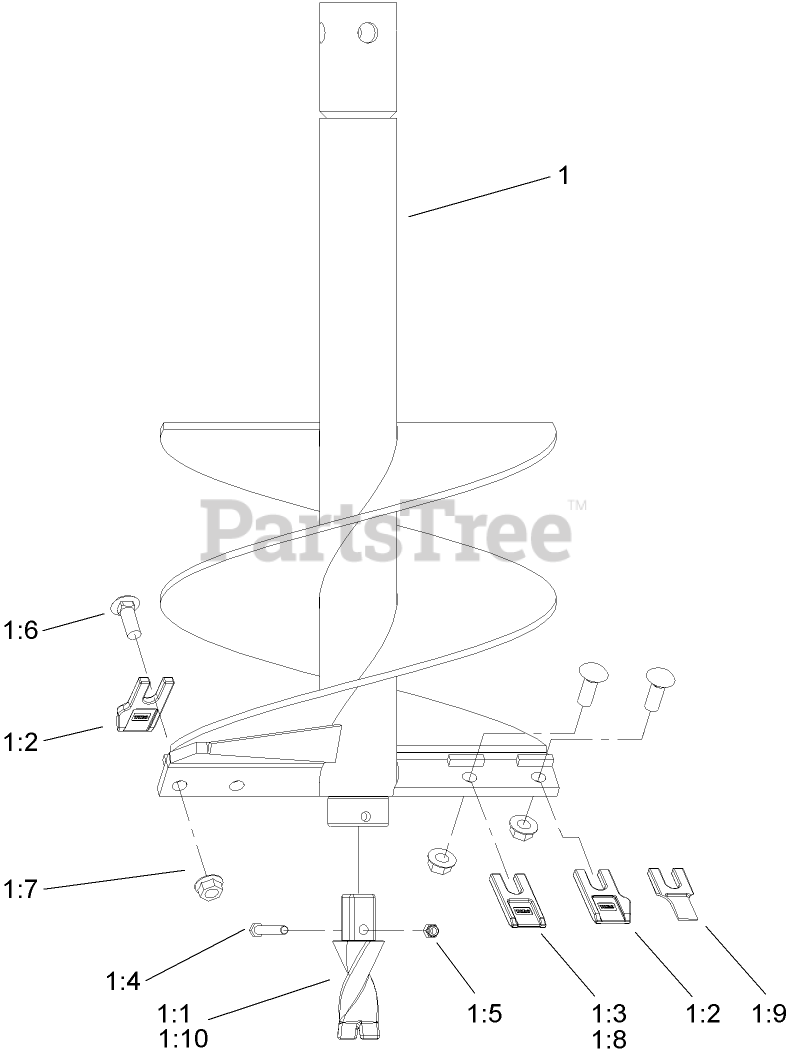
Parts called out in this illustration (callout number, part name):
1	AUGER-12 Inch
1:1	FISHTAIL-SHANK, SQUARE
1:2	TOOTH-AUGER, GAGE
1:3	TOOTH-AUGER, WISDOM
1:4	SCREW-HH
1:5	NUT-LOCK, NI
1:6	SCREW-CARR
1:7	NUT-LOCK, NI
1:8	TOOTH-WISDOM, CARBIDE
1:9	TOOTH-CHISEL, CARBIDE
1:10	PILOT-HARDFACED
